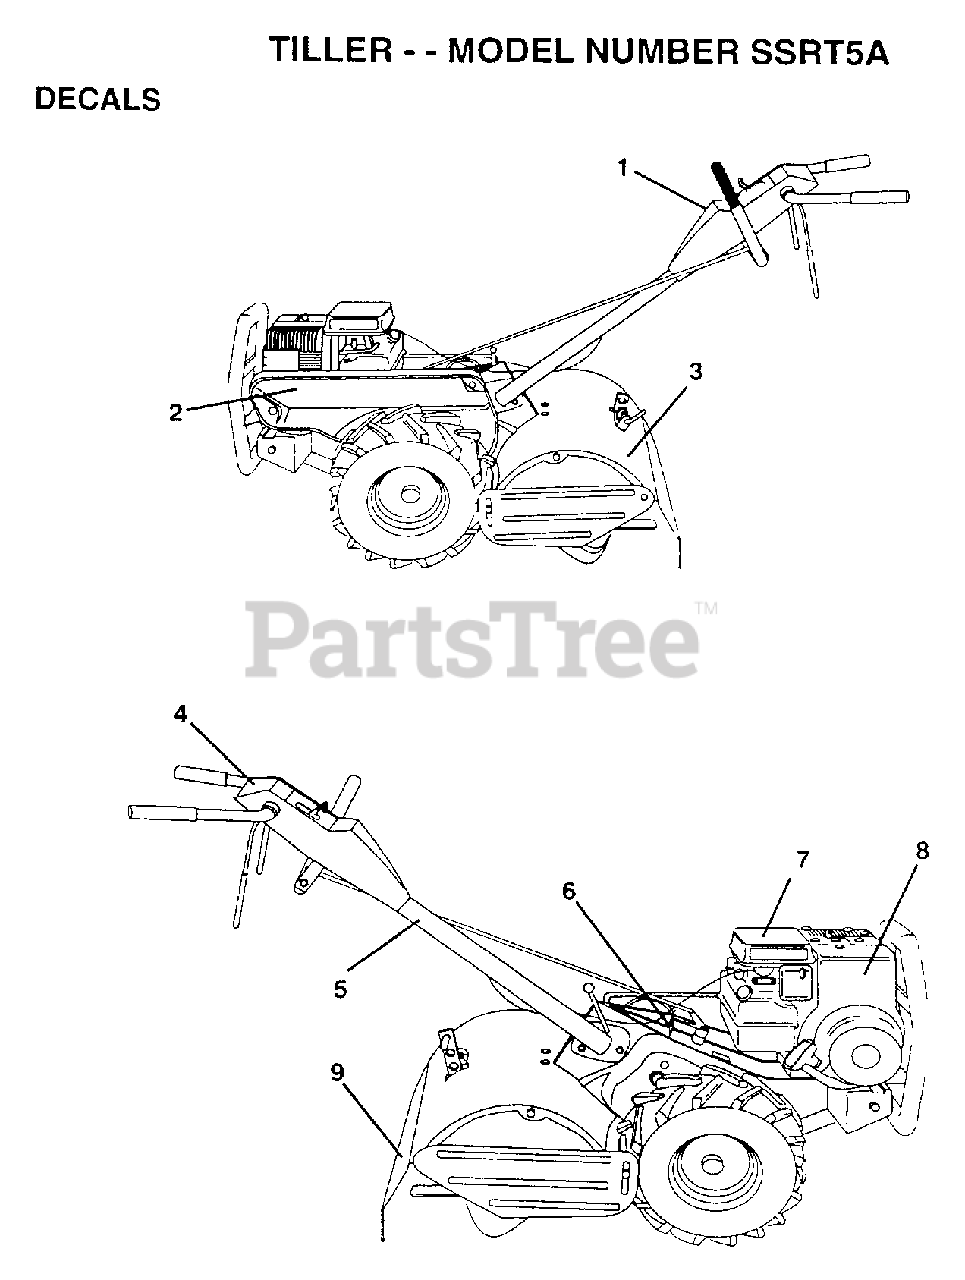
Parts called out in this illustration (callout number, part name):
1	DECAL.PNL.CONTROL
2	DECAL.LOGO.
4	DECAL.INSTRUCTION
5	DECAL TI
6	DECAL CRT
8	DECAL, BRIGGS & STRATTON
9	DECAL TI
